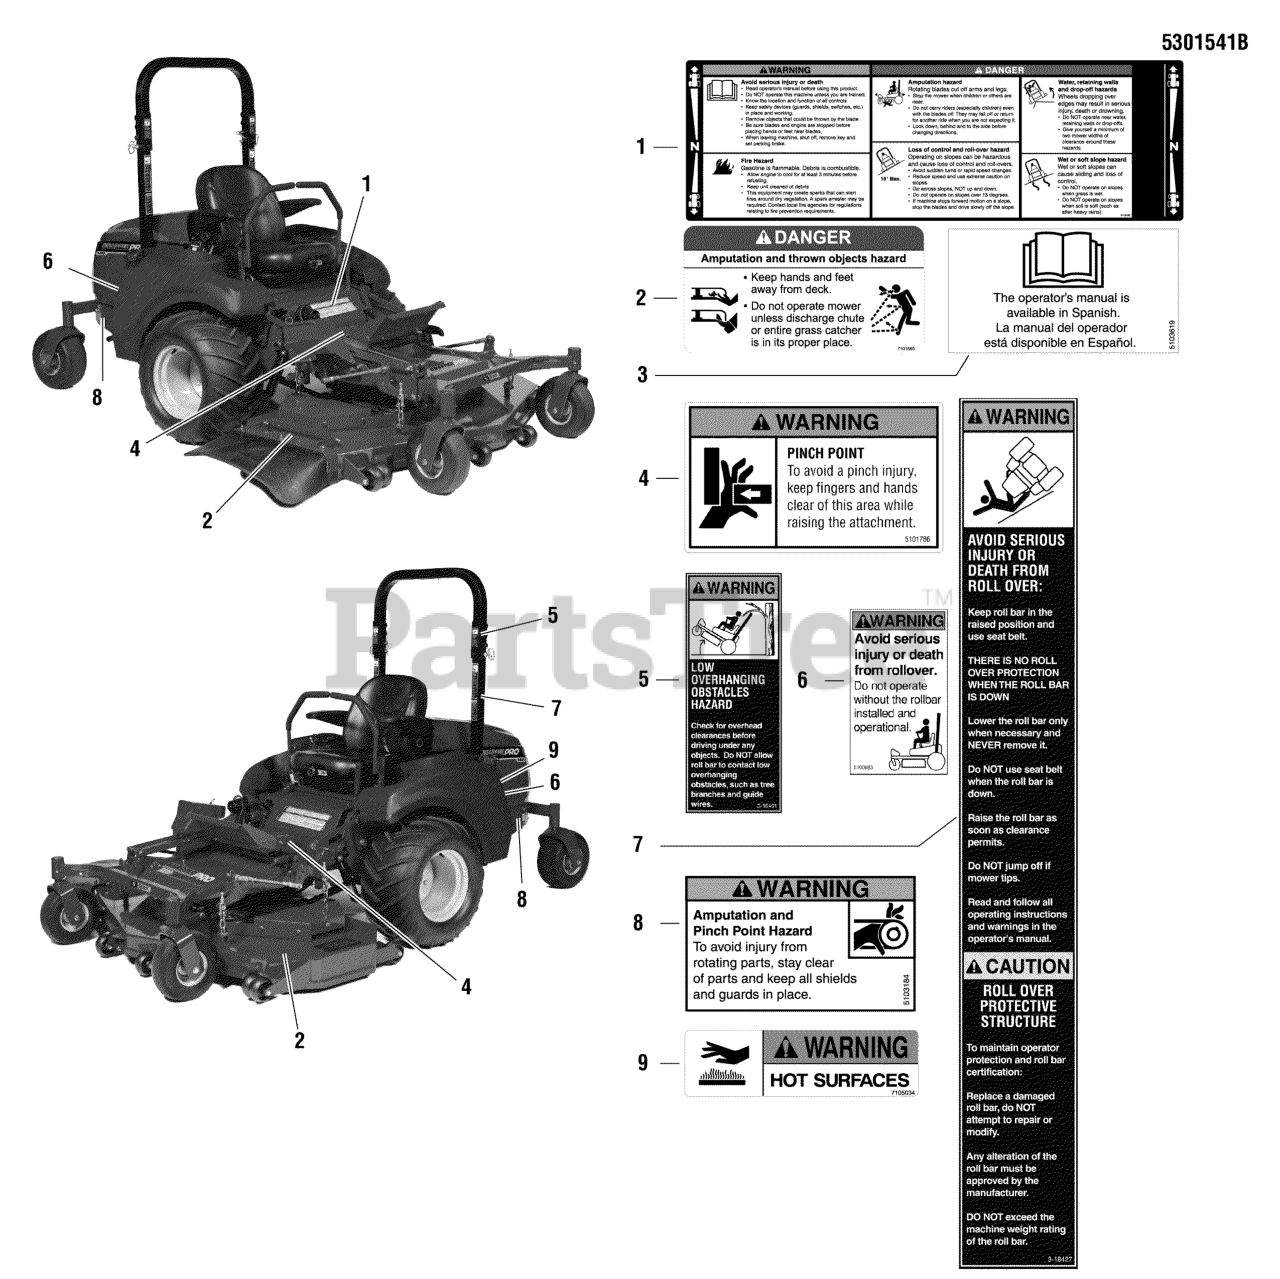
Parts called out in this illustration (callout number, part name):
1	DECAL ASSEMBLY, MAIN SAFETY, 800X (SV)
2	DECAL, DANGER DO NOT OPERATE W/O DEFLECT
3	DECAL, MANUAL AVAIL IN SPANISH
4	DECAL, PINCH POINT, S800X
5	DECAL, WARNING OVERHANG, ROPS
6	DECAL, WARNING, ROLL BAR
8	DECAL, WARNING, HAND IN BELT, ENG
9	DECAL, WARNING, HOT SURFACES
